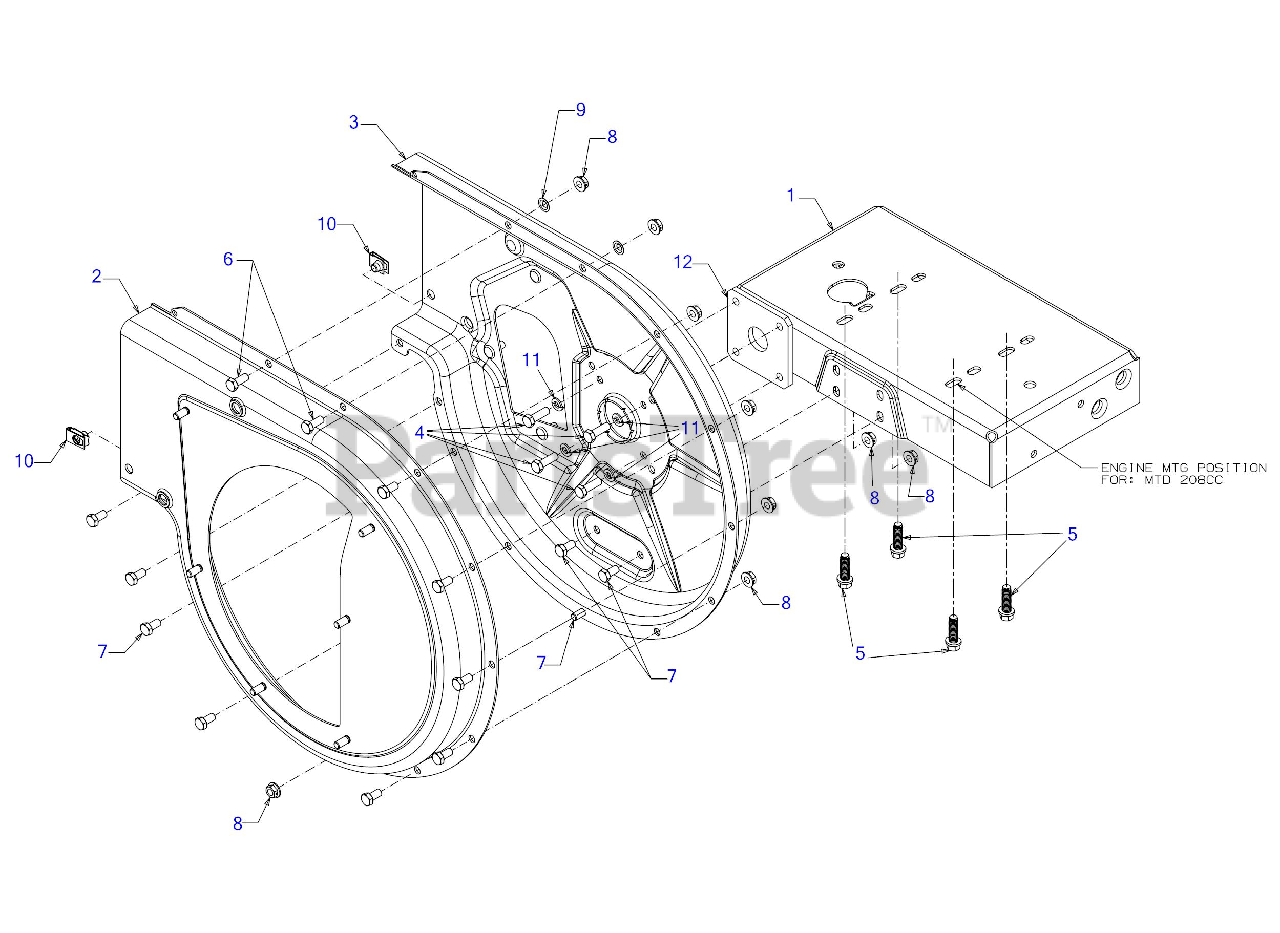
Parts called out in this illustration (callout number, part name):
4	HEX HEAD CAP SCREW 5/16-24 x 1.00 GR5
5	SCREW 3/8-16 x 1.250
6	SCREW 5/16-18 x .75 GR5
7	SCREW 5/16-18X .625 GR5
8	HEX FLANGE NUT
10	U-NUT
11	LOCK WASHER 5/16
